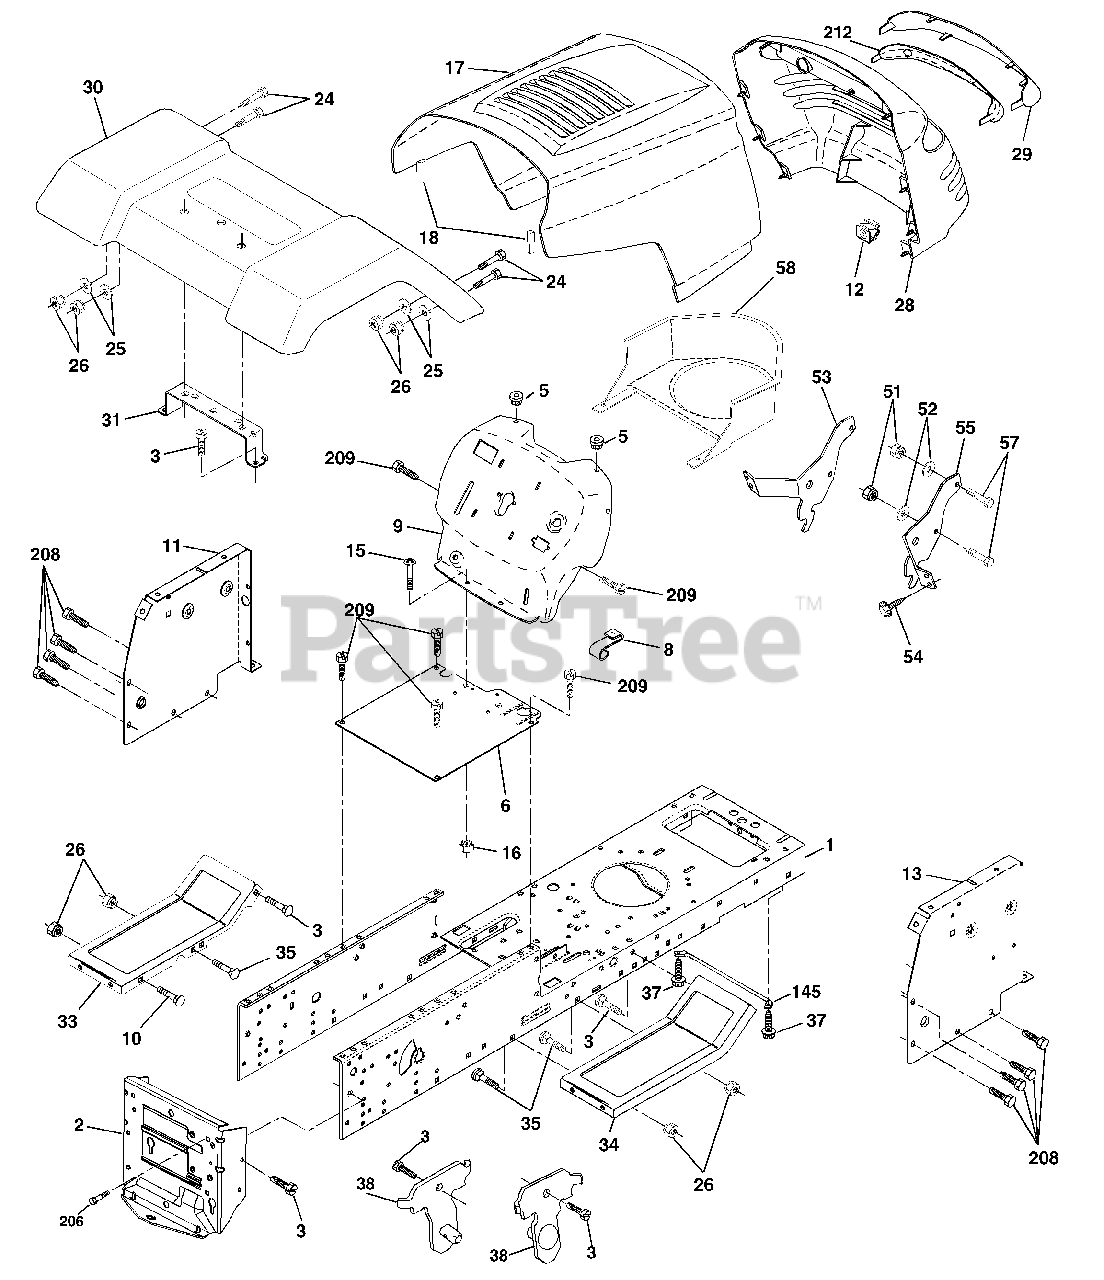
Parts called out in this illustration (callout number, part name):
2	Drawbar, Stretch
3	Screw 3/8-16 x 3/4
5	Bumper,Hood/Dash
8	Clip Retainer Slide-On
10	Bolt, Carriage 3/8-16 x 1
11	Panel Dash LH
12	Clip Tinnerman Grille P.L
13	Panel Slkscr Dash RH
15	Screw Mach TRHD 5/16-18uncx3/4
16	Nut Keps 5/16-18 Unc
17	Hood
18	Bumper Hood
24	Bolt Fin Hex 3/8-16unc X 1 Gr. 5
25	Washer 13/32 X 13/16 X 12 Ga
26	Nut Lock Hex w/Ins 3/8-16 Unc
28	Grille/Lens Asm.
29	Lens Grille Private Label
30	Fender
31	Bracket Fender Repl 109873x
33	Footrest Pnt LH Perf
34	Footrest Pnt RH Perf
35	Bolt Rdhd Sht Sqnk 3/8-16 X3/4
37	Screw Thdrol 5/16-18 x 1/2 TYT
38	Bracket Asm. Pivot Mower Rear
51	Nut Lock W/Insert 1/4-20unc
52	Washer 9/32 x 7/8x16 Ga.
53	Bracket Grille Lh
54	Screw Hex 8-18 x 7/8
55	Bracket Grille Rh
57	Bolt Fin Hex 1/4-20 unc x .75
58	Duct Air Engine PL/LT
145	Rod Pivot Chassis/Hood
206	Bolt Shoulder 5/16-18
208	Screw Thdrol 3/8-16 x 1/2
209	Screw Hex Wsh Thdrol 3/8-16
212	Insert Lens Reflect
